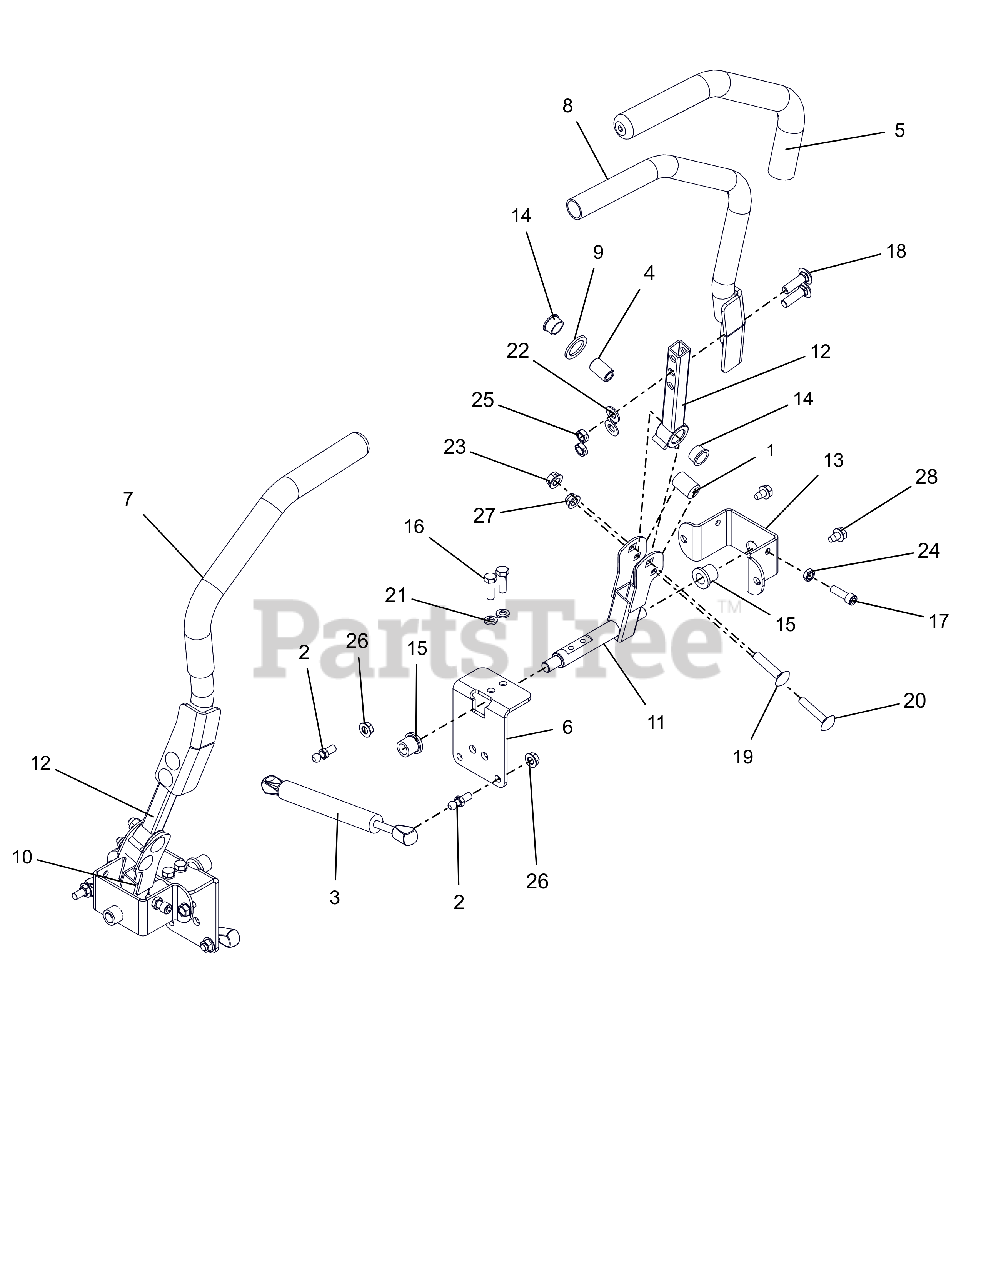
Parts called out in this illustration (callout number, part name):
1	BSHG,ECCEN .328X.750X1.01 PM
2	STUD- BALL
3	DAMPER, STABILUS
4	SPACER, .375X.625X.970 (PM)
5	GRIP, HANDLEBAR 15" FOAM
6	BRKT, STEEERING
7	WLDMT, STEERING HANDLE RH
8	WLDMT, STEERING HANDLE LH
9	WASHER, FRICTION .875X1.25X.10
10	WLDMT,STEERING ARM LOWER RIGHT
11	WLDMT,STEERING ARM LOWER LEFT
12	WLDMT, UPPER CONTROL ARM
13	BRKT, STEERING
14	BSHG-FLG, .625X.75X.450X.875
15	BSHG-FLG .515X.750X.745X1.00NY
16	BLT-HEX .31-18X1.00 GR8 YWZC
17	SCR, SKH .312-18X1.00 G8 SS
18	BLT,RHSSN .38-16X1.25 G5 BFP
19	BLT,RHSSN .38-16X1.75 G5 BFP
20	BLT,RHSSN .31-18X1.75 G5 BFP
21	@WSHR-LK .31X.078 REG YWZC
22	@WSHR-FL-STL.406X.812X.065 YWZ
23	NUT-LK-CTR-FLG .38-16 YWZC
24	NUT- JAM .312-18 YWZC
25	@NUT-LK-CTR-JAM .375-16 YWZC
26	@NUT-LK-TOP-FLG .31-18 YWZC
27	@NUT-LK-NYL-FLG .31-18 YWZC
28	@SCR-TAP .31-18X.50 HWH TR YWZ
